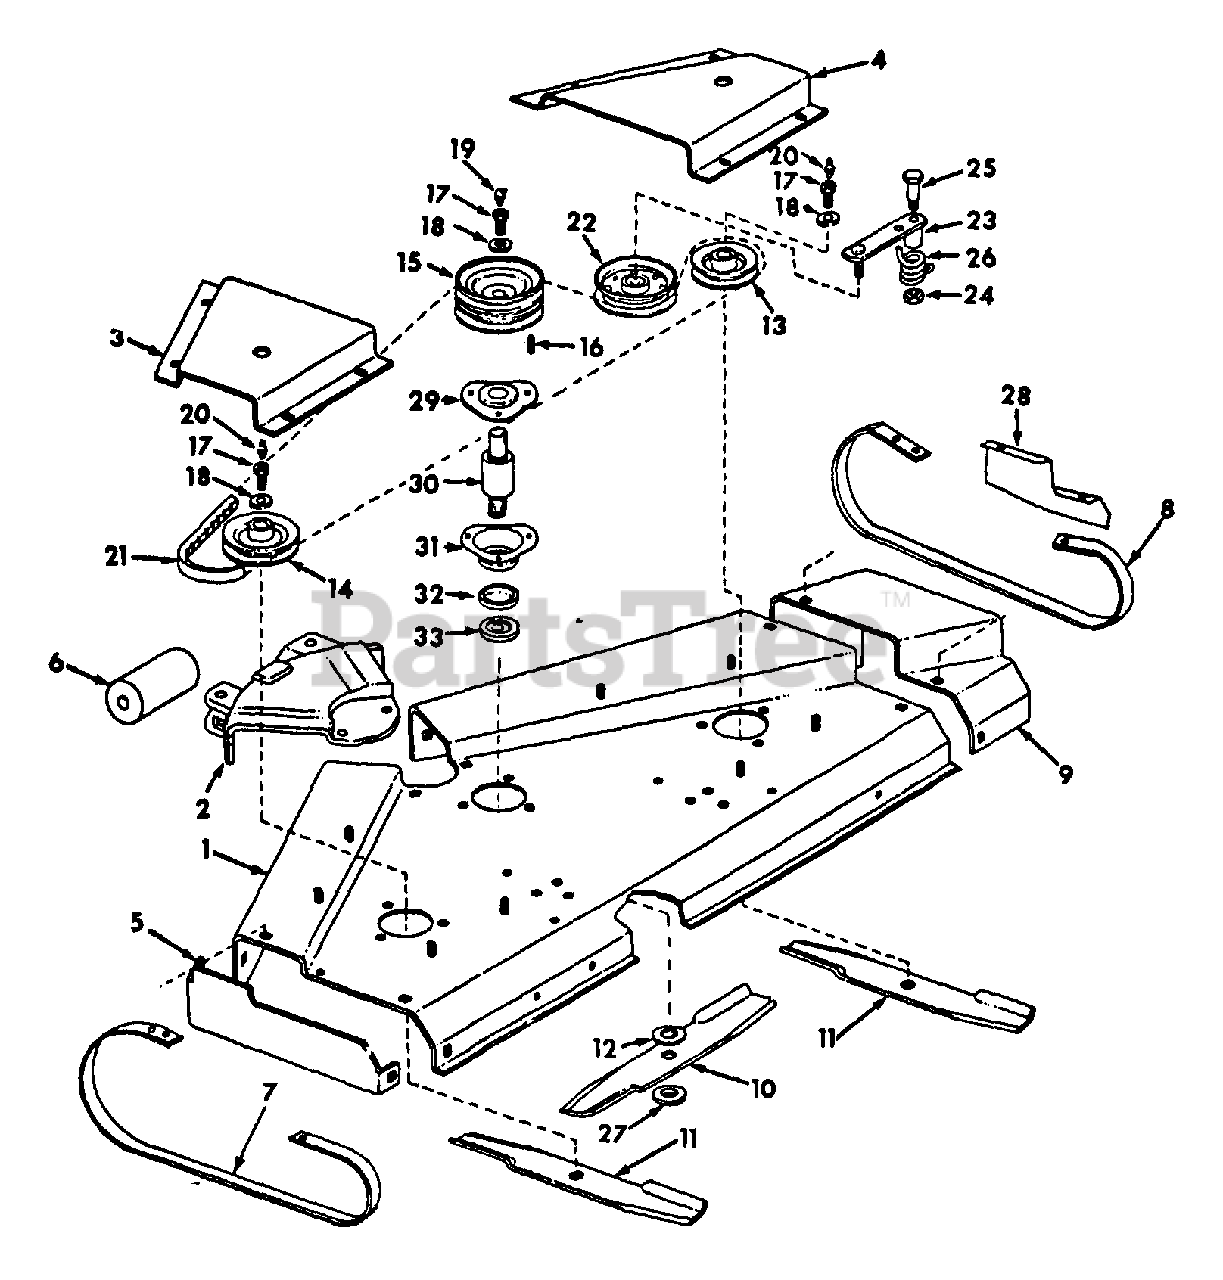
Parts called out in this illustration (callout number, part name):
1	HOUSING ASSY
2	HOUSING, CENTER
3	SHIELD, LH
4	SHIELD, RH
5	SIDE HOUSING LH
6	ROLLER, FRONT
9	SHIELD, DISCHARGE
10	BLADE, CENTER -HARD SURFACED- w/489392-R1
10	BLADE, CENTER -w/490474-R1
11	BLADE, OUTER -HARD SURFACED- w/489393-R1
11	BLADE, OUTER -w/490475-R1
12	WASHER, BLADE FRICTION
13	PULLEY, RH DISCHARGE OUTER
14	PULLEY, LH OUTER
15	PULLEY, CENTER
16	KEY, 1/4 x 3/4 SQ-PARALLEL
17	BOLT, END
18	WASHER, SPINDLE
19	FITTING, 3/8 DRIVE TYPE 45ø ANGLE LUB - END BOLT FOR CENTER ROTOR
20	FITTING, 5/16 DRIVE TYPE STR LUB END BOLT FOR OUTER ROTORS
21	BELT, SPINDLE DRIVE
22	PULLEY, FLAT IDLER
23	ARM ASSY, IDLER
24	NUT, CENTER LOCK
25	BOLT, IDLER ARM PIVOT
26	SPRING, TORSION
27	WASHER, 25/32 x 2 x 11 GA - BLADE DRIVE DISC SPACING
29	CAP, SPINDLE HOUSING
30	BEARING, BALL FAN & PUMP
31	HOUSING, SPINDLE
32	CUP, SPINDLE
33	SPACER, BLADE
